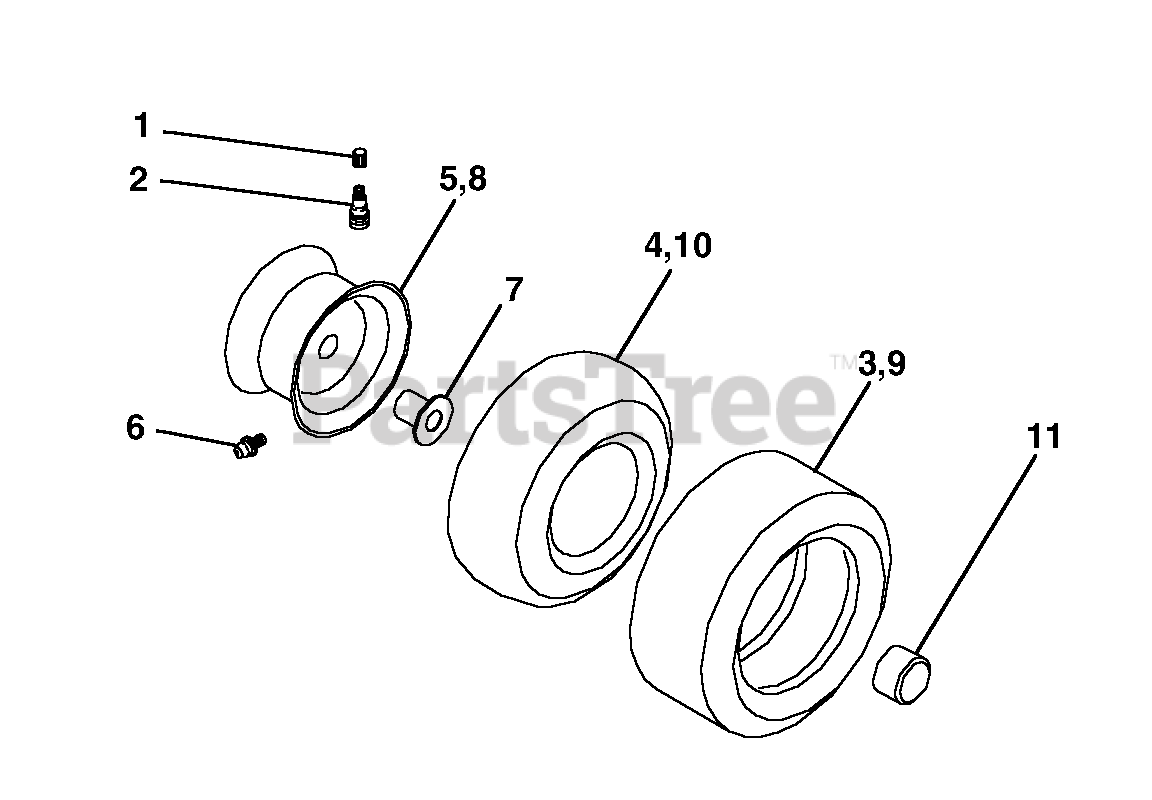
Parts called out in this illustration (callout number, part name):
1	Cap Valve Tire
2	Stem Valve
3	Tire F Ts 15 X 6 0 - 6 Service
4	Tube Front (Service Item Only)
5	Rim Asm 6"front Silver Service
6	Fitting Grease (Front Wheel Only)
7	Bearing Flange (Front Wheel Only)
8	Rim Asm 8"rear Silver Service
9	Tire R Ts 20x10-8 C Service
10	Tube Rear (Service Item Only)
11	Cap Axle Blk 1 50 X 1 00
